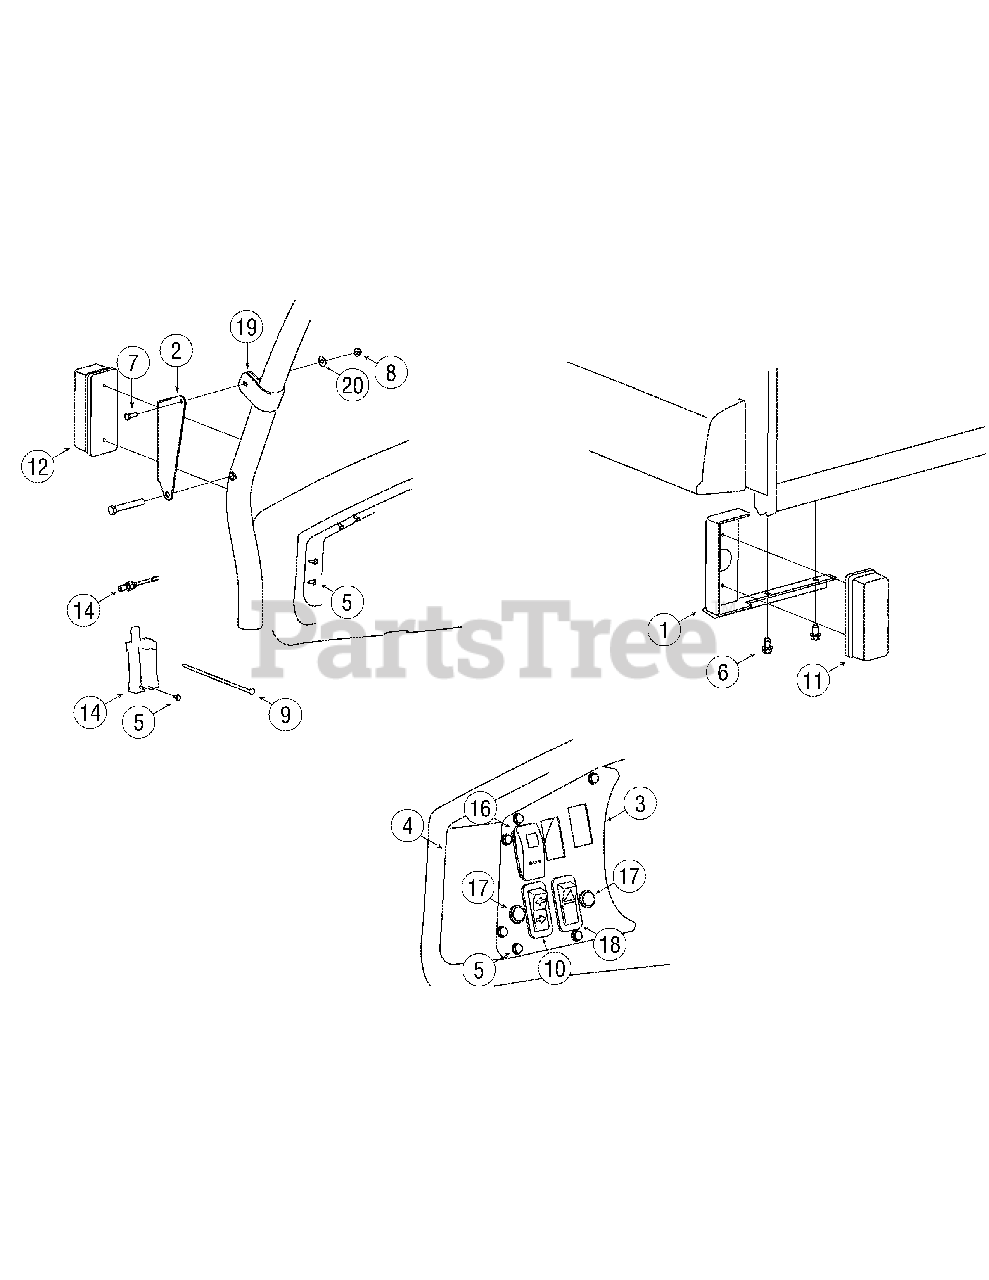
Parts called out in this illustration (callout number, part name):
1	Bracket., Assy., Lgt., RR, LH
4	Bracket., Switch, Lgt., Ind., UV
5	Screw, AB, #10-16 x .500
6	Screw, tt, 3/8-16 x .750
7	Hhcs, 1/4-20 x .75
8	Nut, Flglk., 1/4-20
9	Cable, Tie
10	Switch, Ind., Directional
11	Lamp, UV, Stop/Tail/Turn
12	Lamp, UV, Turn
14	Switch, UV, Brake
16	Switch, Master Light
17	Lamp, Ind., Green, Incadescent
18	Switch, Hazard, Dbl. Pole
19	Clamp, Tube, OPS
20	Wash., Flat, .260 x .720 x .060
